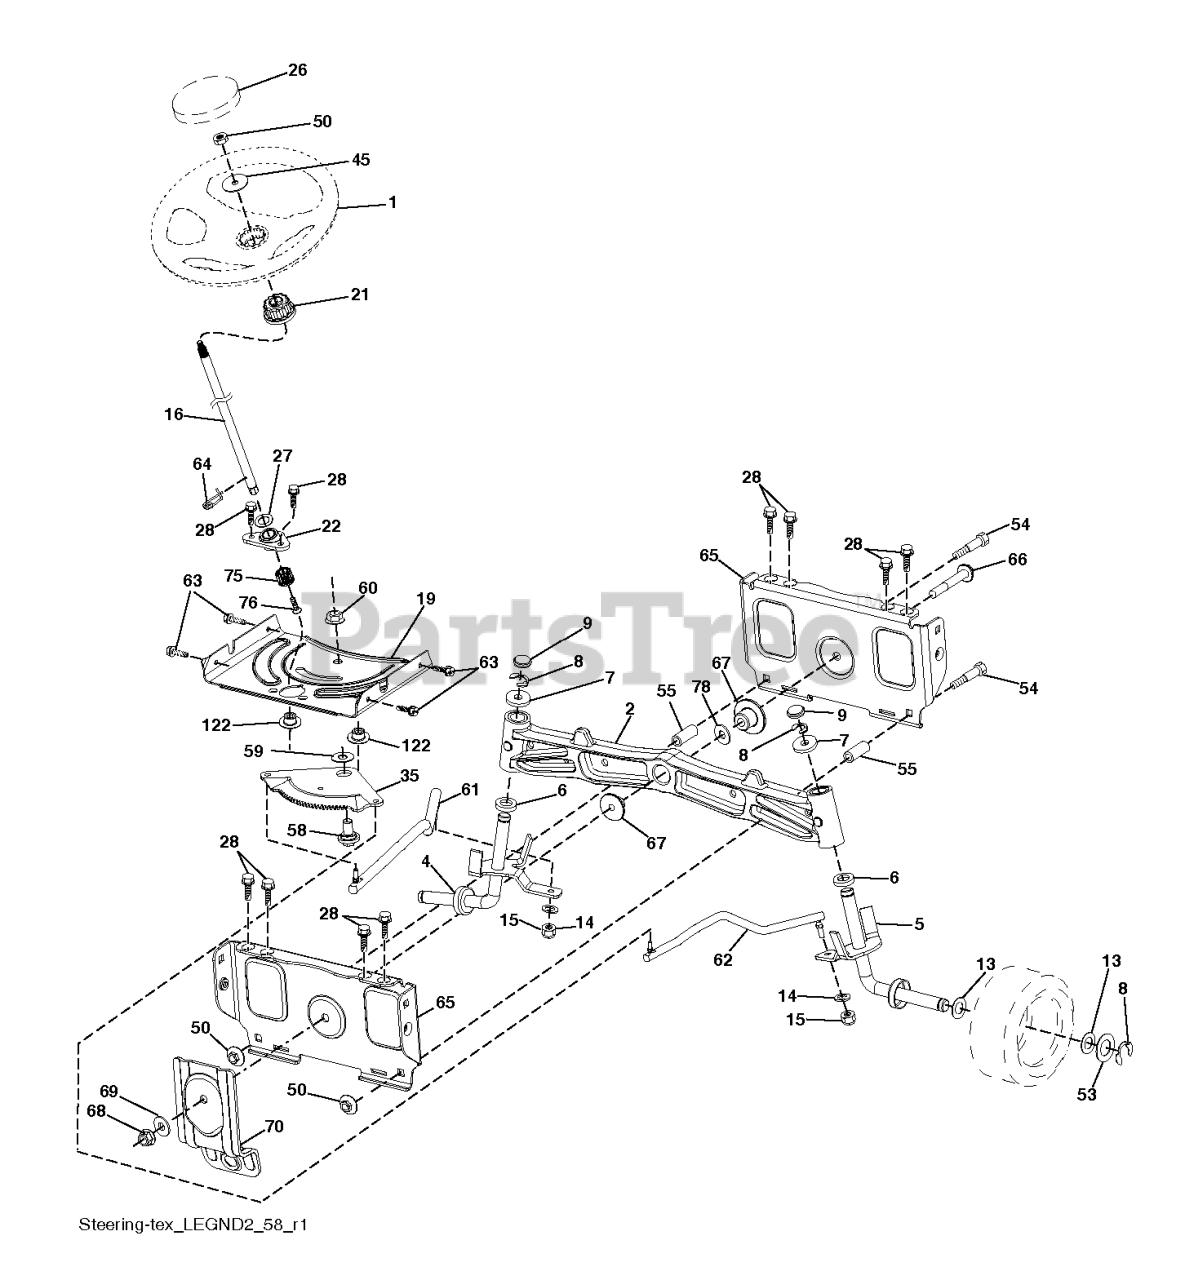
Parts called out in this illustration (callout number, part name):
1	WHEEL.STEER.HUSQ.SR.498.OVMLD
2	AXLE.CAST.IRON
4	SPINDLE.WELDED.LH.16"TEX
5	SPINDLE.WELDED.RH.16"TEX
6	WASHER THRUST
9	CAP.SPINDLE.BLACK
15	NUT CROWNLOCK 3/8-24
16	SHAFT.STEER.2HIGH.SPLND.PLATED
19	PLATE.STEER.DDL.NLT/NG
21	ADAPTER.WHEEL.STEER.SPLND.ALUM
22	BEARING.SUBASM.SHAFT.STEER.LOW
26	INSERT.CAP.WHL.STRG.HUSQ.PREM
28	SCREW, 3/8-16X3/4
35	GEAR.SECTOR.PLATE.DDL.
45	WASHER.3/8ID.2-3/8OD.12GA.PLTD
50	NUT LOCK FLG 3/8-16 UNC
53	WASHER.HARDENED
55	SPACER.BRACE.AXLE
58	BOLT.SHOULDER.SECTOR.P
59	WASHER.THURST.SECTOR.S
60	NUT FLANGE LOCK 5/8-11
61	Links
62	Links
63	SCREW
64	RETAINER.CLIP.SPRING.S
65	BRACE.AXLE.FRONT.NLT/N
66	BOLT HEX FGHD 7/16-14 X 3 SERR
67	BUSHING.PM.FRONT AXLE
68	NUT.LOCK.FLANGE.7/16
69	WASHER.1.5X.505X.118
70	BRACKET.FRT.DECK.SUSP.RR.MT431
75	PINION.ZINC PLATED
76	SCREW HEAD SOCKET LRVB
78	THRUST WASHER
122	CAP.GEAR.SECTOR.TEX
